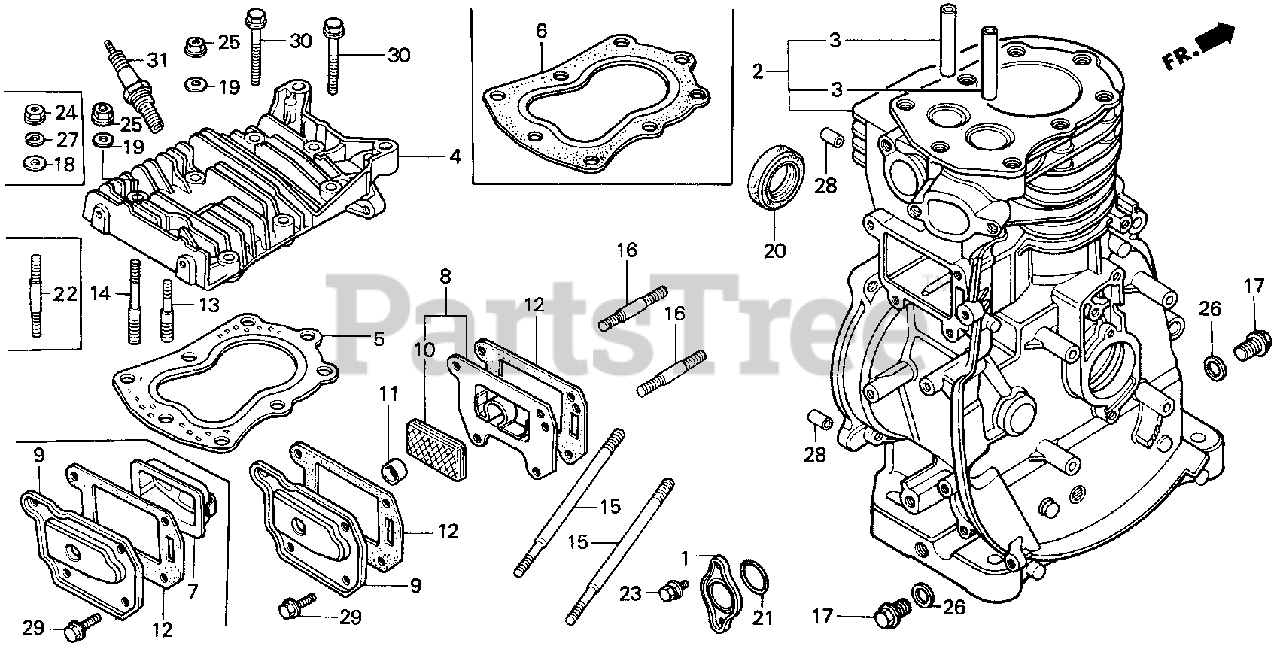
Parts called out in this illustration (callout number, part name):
1	COVER, OIL PAN
2	CYLINDER (CAMSHAFT P.T.O.)
3	GUIDE, VALVE
4	CYLINDER HEAD
5	GASKET, CYLINDER HEAD
6	GASKET, CYLINDER HEAD
8	CASE, BREATHER
9	COVER, TAPPET
10	FILTER, BREATHER
11	SEAL, BREATHER
12	GASKET, TAPPET COVER
13	BOLT, STUD (M8XM10X63)
14	BOLT, STUD (M8XM10X81)
15	BOLT, STUD (8X110)
16	BOLT, STUD (8X35)
17	BOLT, DRAIN PLUG
19	WASHER (8MM)
20	OIL SEAL (25X41X6)
21	O-RING (27X2.0)
23	BOLT-WASHER (6X12)
25	NUT-WASHER (8MM)
26	WASHER, DRAIN PLUG (12MM)
28	PIN A, DOWEL (8X14)
29	BOLT, FLANGE (6X12)
30	BOLT, FLANGE (8X50) (NOT AVAILABLE)
31	SPARK PLUG (BR-4HS) (NGK)
31	SPARK PLUG (W14FR-U) (DENSO)
